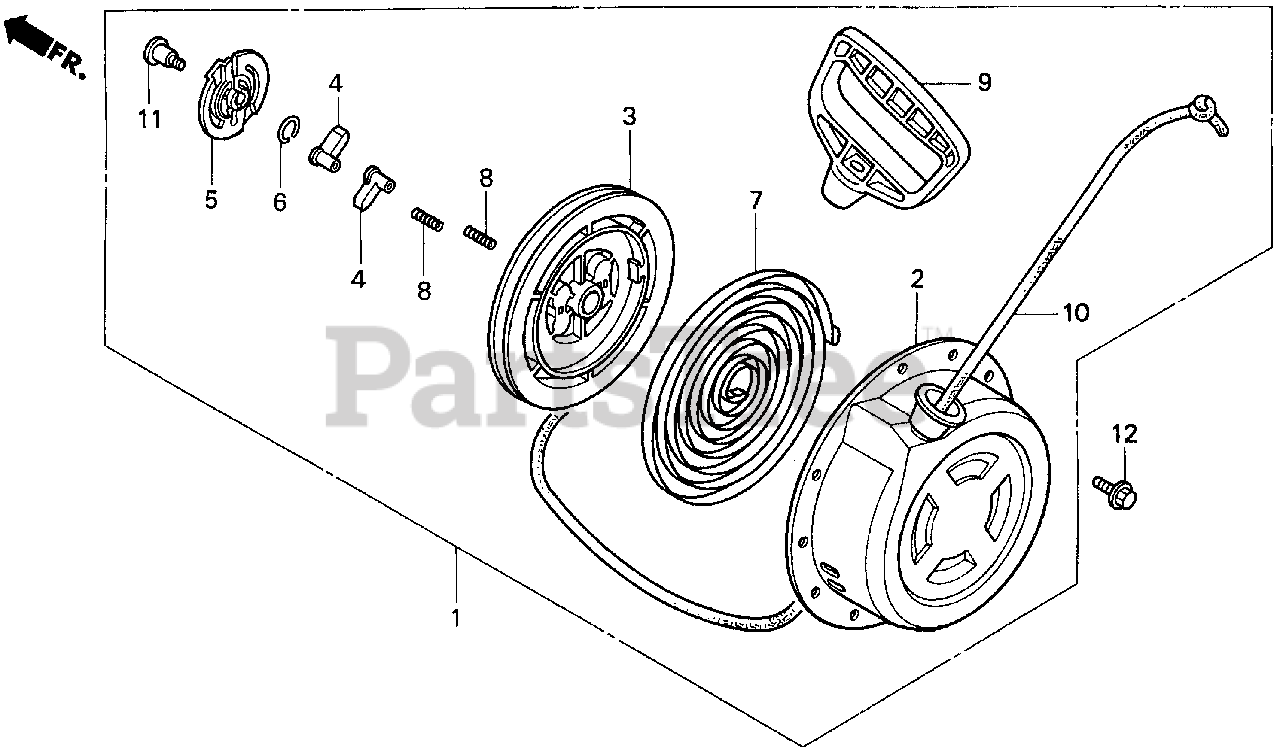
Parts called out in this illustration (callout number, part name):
1	STARTER ASSY., RECOIL *R280* (POWER RED)
2	CASE, RECOIL STARTER
3	REEL, RECOIL STARTER
4	RATCHET, STARTER
5	GUIDE, RATCHET
6	SPRING, FRICTION
7	SPRING, RECOIL STARTER
8	SPRING, RETURN
9	GRIP, STARTER
10	ROPE, RECOIL STARTER (NA USE ALT:08550-ZG921-11)
11	SCREW, SETTING
12	BOLT, FLANGE (6X10)
